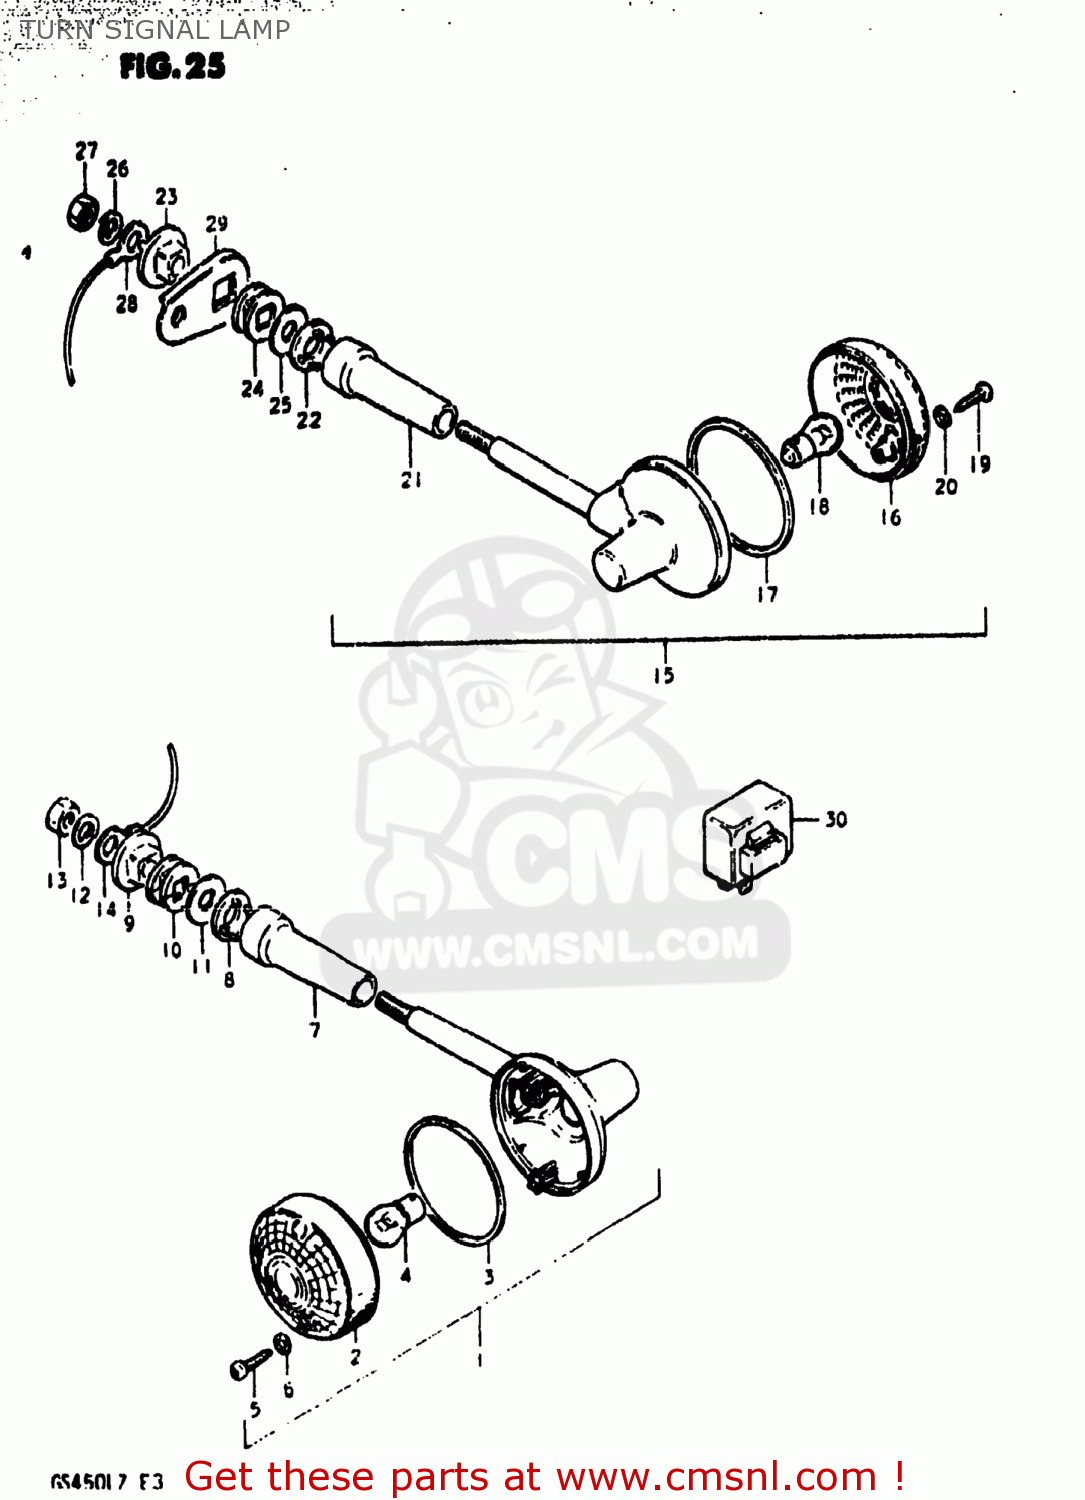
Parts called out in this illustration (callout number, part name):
1	LAMP ASSEMBLY,REAR TURN SIGNAL
2	LENS
3	GASKET (NAS)
4	BULB(12V23W,STANLEY,A4577A)
5	SCREW
6	GASKET (NAS)
7	COVER,STAY
8	SPACER
9	SPACER
10	CUSHION
11	WASHER (10.5X30X2.3)
12	LOCK WASHER
13	NUT
14	WIRE
15	LAMP ASSEMBLY,REAR TURN SIGNAL
16	LENS
17	GASKET (NAS)
18	BULB(12V23W,STANLEY,A4577A)
19	SCREW
20	GASKET (NAS)
21	COVER,STAY
22	SPACER
23	SPACER
24	CUSHION
25	WASHER (10.5X30X2.3)
26	LOCK WASHER
27	NUT
28	WIRE
29	BRACKET,RR TURN SIGNAL LAMP
30	RELAY,TURN SIGNAL
